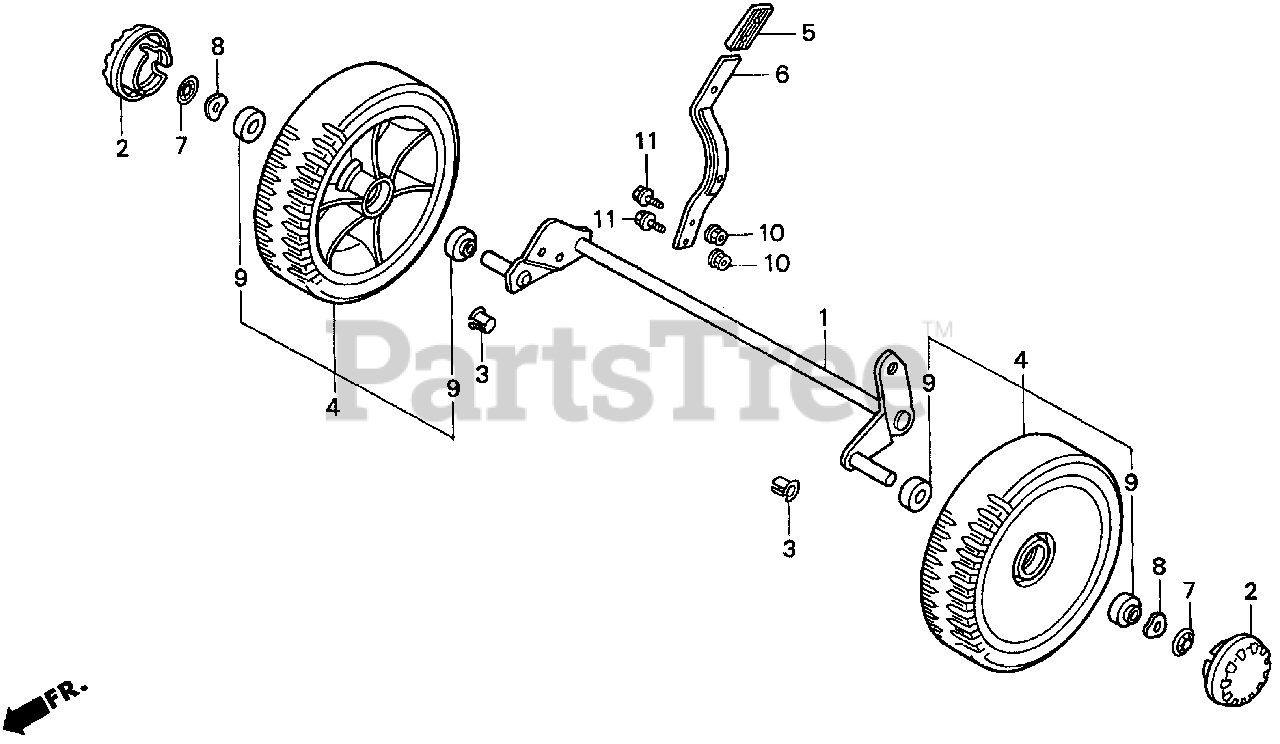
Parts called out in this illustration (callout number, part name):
1	SHAFT, RR. AXLE
2	CAP, WHEEL
3	BUSH, RR. AXLE SHAFT
4	WHEEL (200X45)
5	GRIP, ADJUSTER
6	LEVER, HEIGHT ADJUSTER
7	NUT, PUSH (12.7MM)
8	WASHER, SPRING
9	BEARING, RADIAL BALL
10	NUT, FLANGE (6MM)
11	BOLT, FLANGE (6X14)
